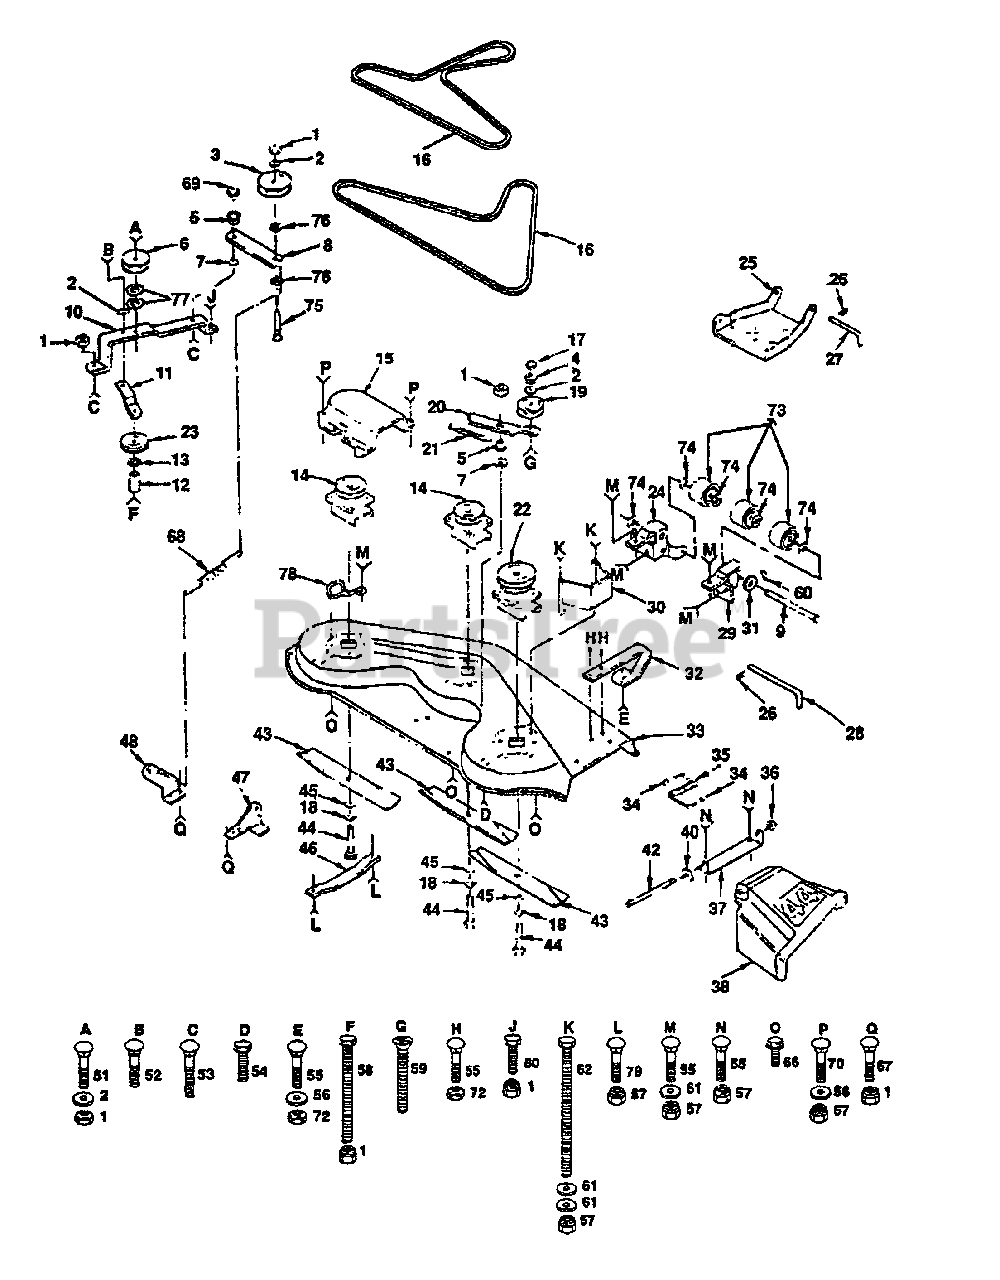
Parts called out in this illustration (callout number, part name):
1	Nut, Crownlock 3/8-16
2	Washer 13/32 x 1 x 14 Gauge
3	Pulley, Idler
4	Washer, Lock 3/8
6	Pulley, Idler
7	Washer, Wear
8	Arm, Idler
9	Pin, Pivot
10	Bar, Support, Idler
11	Brace, Idler, Deck
13	Washer 13/32 x 13/16 x 16 Gauge
14	Mandrel. Secondary
17	Nut, Hex 3/8-16
18	Washer, Lock 3/8
19	Idler, Flat
20	Arm, Idler, Deck
21	Spring, Extension
22	Mandrel, primary
23	Pulley, Idler
24	Bracket, Lift, L.H.
25	Link, Parallel
26	Retainer, Spring
27	Pin, Front Hinge
28	Pin, Rear Hinge
29	Bracket, Lift, L.H.
30	Guard, Belt, R.H.
31	Washer 15/32 x 1 x 16 Gauge
32	Runner, R.H.
33	Housing, Mower
34	Cap, Sleeve
35	Spring
37	Bracket, Deflector
38	Guard, Discharge
40	Washer 11/32 x 5/8 x 16 Gauge
42	Rod, Hinge
43	Blade, Mower
44	Bolt, Hex 3/8-24 x 1-1/2 Grade 5
45	Washer 13/32 x 1-1/4 x 12 Gauge
46	Runner, L.H.
47	Bracket, Suspension, Rear, R,H.
48	Bracket, Suspension, Rear, L.H.
51	Bolt, Carriage 3/8-16 x 1-3/4
52	Bolt, Carriage 3/8-16 x 1
53	Soft, Carriage 3/8-16 x 1-1/2
54	Bolt, Hex 38-16 x 1-1 /4
55	Bolt, Carriage 5/16-18 x 3/4
56	Washer 11/32 x 11/16 x 16 Gauge
57	Nut, Crownlock 5/16-18
58	Bolt, Hex 3/8-16 x 3
59	Screw, Flat Head 3/8-16 x 2
60	Pin, Cotter
61	Washer 11/32 x 3/4 x 16 Gauge
62	Bolt, Hex 5/16-18 x 5
66	Screw, Hex Washer Thread Rolling 3/8-16 x 3/4
67	Bolt, Carriage 3/8-16 x 3/4
68	Spring, Extension
69	Nut, Centerlock 38-16
70	Bolt, Carriage 5/16-18 x 3/4
72	Locknut 5/16-18
73	Roller, Nose
74	Washer 15/32 x 1 x 10 Gauge
75	Bolt, Carriage 3/8-16 x 2-1/2
76	Washer 13/32 x 3/4 x 10 Gauge
77	Washer 13/32 x 7/8 x 10 Gauge
78	Keeper, L.H., Mandrel
79	Bolt, Carriage 5/16-18 x 5/8
80	Bolt, Hex, Fin 3/8-16 x 1
